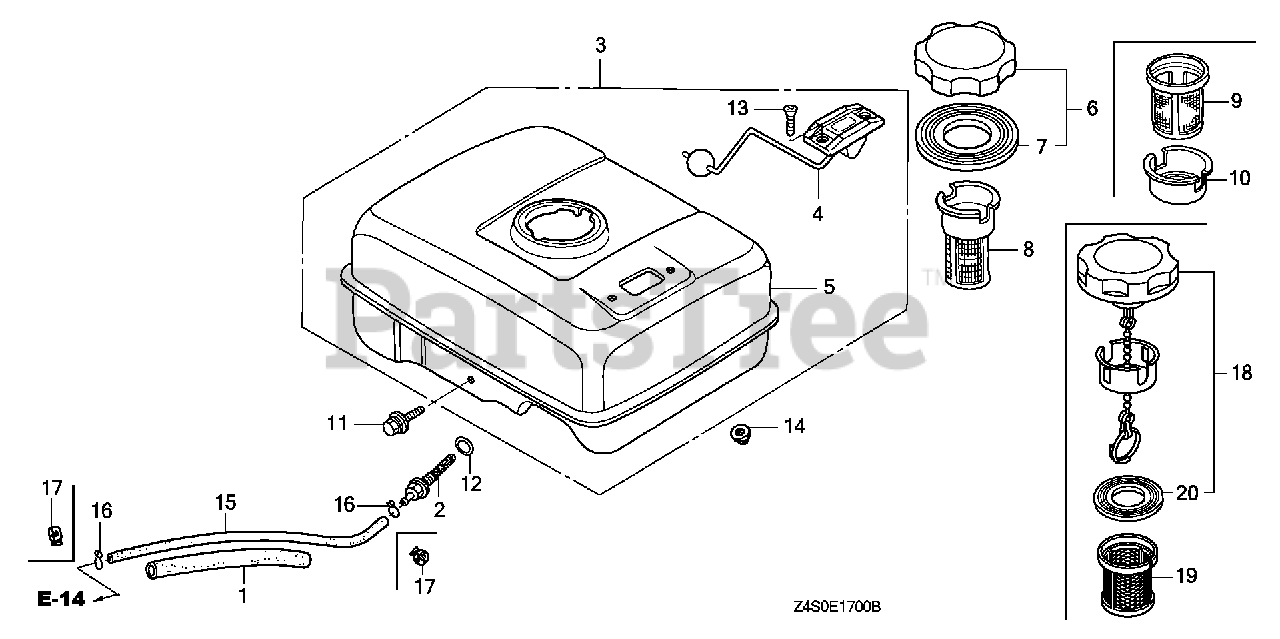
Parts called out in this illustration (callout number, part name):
1	RUBBER, SUPPORTER (107MM)
2	JOINT, FUEL TANK
5	TANK, FUEL *NH31* (MCKINLEY WHITE)
6	CAP, FUEL FILLER (CHROME PLATED)
7	GASKET, FUEL FILLER CAP (39X62X3) (TOUYOUSYA)
9	FILTER, FUEL
10	HOLDER, FUEL FILTER
11	BOLT, FLANGE (6X34)
12	O-RING (13.5X1.5) (ARAI)
12	O-RING (14MM) (NOK)
14	NUT, FLANGE (6MM)
15	TUBE, FUEL (4.5X140) (FKM)
15	BULK HOSE, FUEL (4.5X3000) (4.5X140)
16	CLIP, TUBE (B8)
17	CLAMP, TUBE (D8)
18	CAP, FUEL FILLER (CHROME PLATED)
18	CAP, FUEL FILLER
19	FILTER, FUEL
20	GASKET, FUEL FILLER CAP (39X62X3) (RADICON)
20	GASKET, FUEL FILLER CAP (39X62X3)
